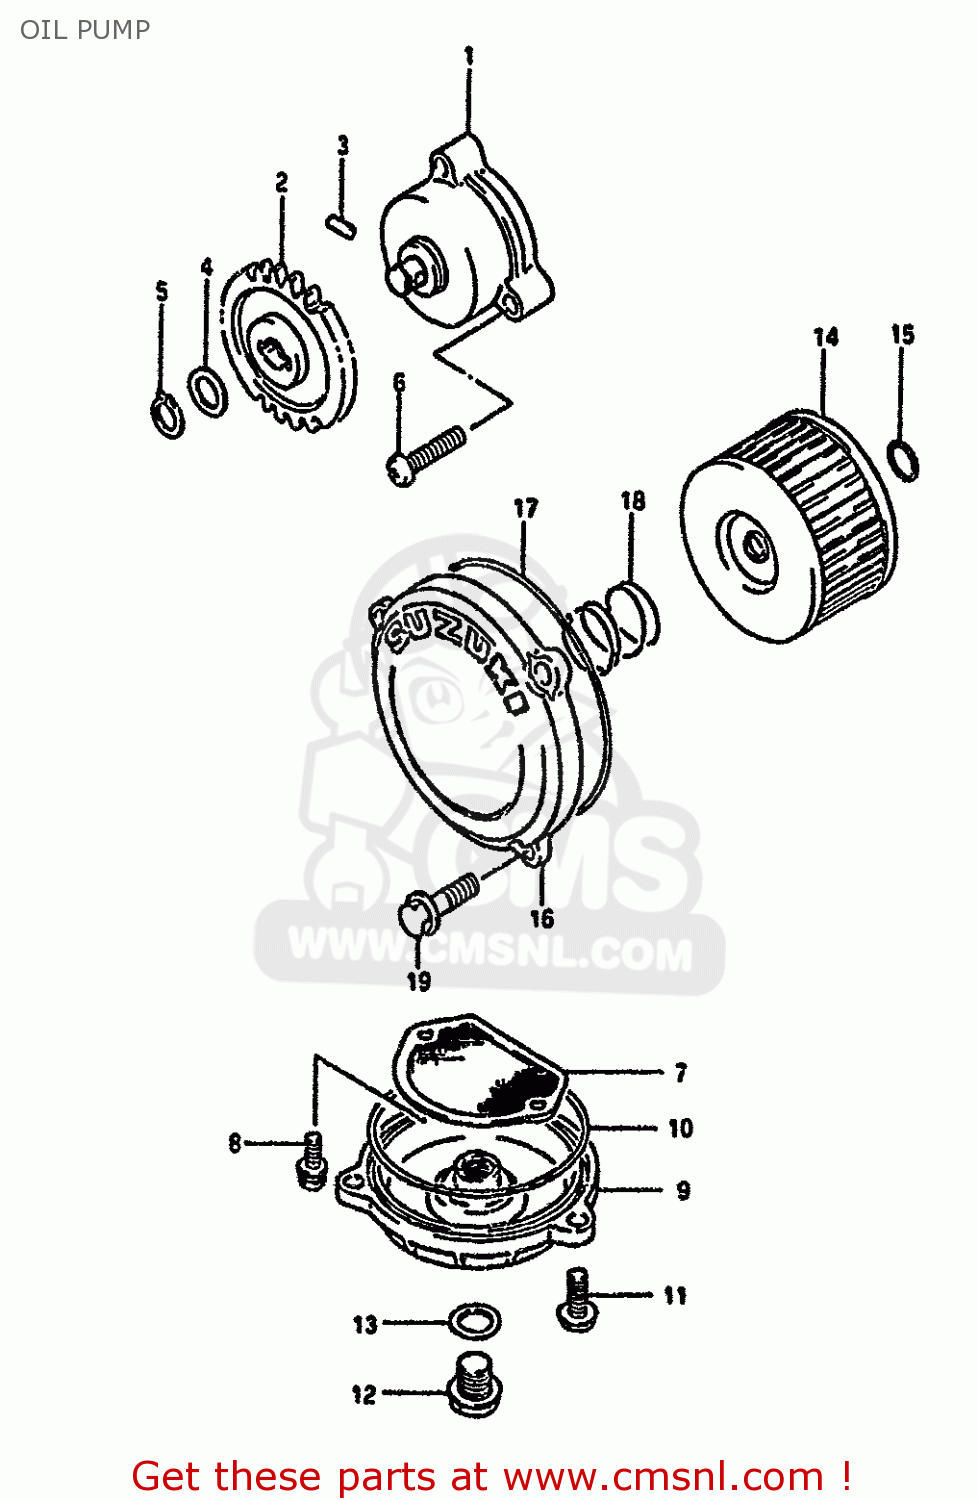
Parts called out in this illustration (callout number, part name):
1	PUMP ASSY,ENGINE OIL
2	GEAR,OIL PUMP DRIVEN
3	PIN(4X15.8)
4	SHIM
5	CIRCLIP,10MM
6	SCREW
7	STRAINER,ENGINE OIL
8	SCREW
9	CAP,OIL STRAINER
10	O RING(D:2.4,ID:85)
11	BOLT
12	PLUG
13	GASKET(14X19.2X2) (NAS)
14	FILTER,ENGINE OIL
15	O RING(D:2.4,ID:15.8)
16	CAP,OIL FILTER
17	O RING(D:2.4,ID:73)
18	SPRING
19	BOLT
